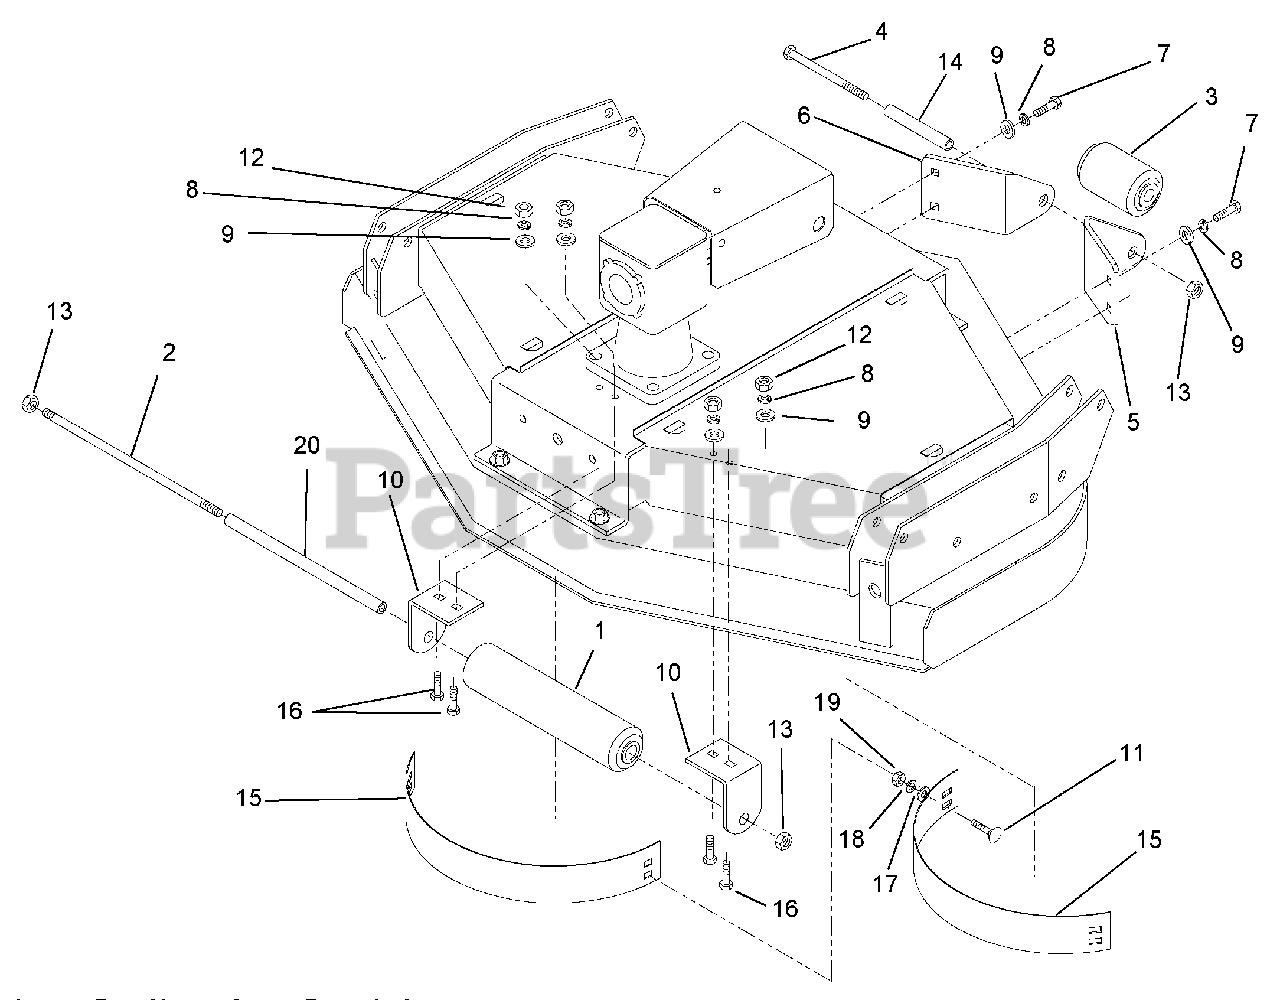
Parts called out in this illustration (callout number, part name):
1	Roller, Large
3	Roller, Small
4	Cap Screw, Hex Head .50-13 x 6.5
5	Mount, Roller Right
6	Mount, Roller Left
7	Cap Screw, Hex Head .38-16 x 1
8	Washer, Lock .38
9	Washer, Flat .38
10	Bracket, Roller
11	Bolt, Carriage .38-16 x .75
12	Nut, Hex .38-16
13	Nut, Lock .50-13
15	Baffle, Bolt-On Rear
16	Bolt, Carriage .38-16 x 1
17	Washer, Flat .38
18	Washer, Lock .38
19	Nut, Hex .38-16
